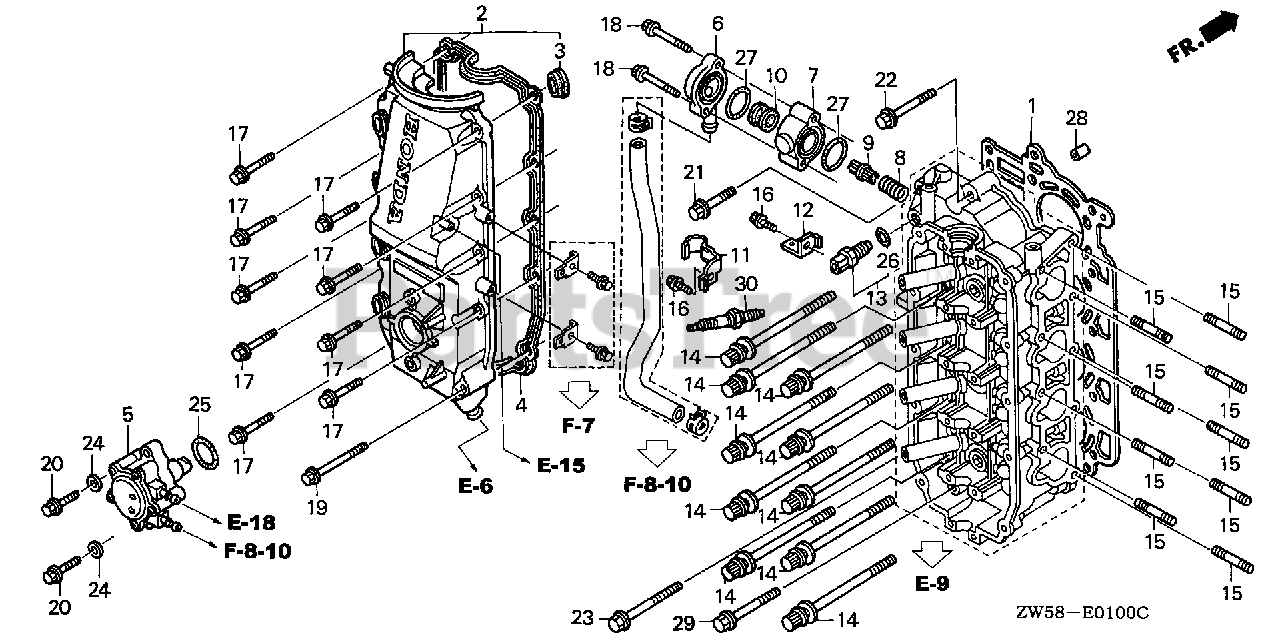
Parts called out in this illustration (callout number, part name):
1	GASKET, CYLINDER HEAD
2	COVER, HEAD *NH8* (DARK GRAY)
3	SEAL, SPARK PLUG TUBE (NOK)
4	GASKET, HEAD COVER
5	PUMP ASSY., FUEL (MSDS)
6	COVER, FLUSH VALVE
7	SPACER, FLUSH VALVE *NH8* (DARK GRAY)
8	SPRING, FLUSH VALVE
9	VALVE, RELIEF
10	GASKET, RELIEF VALVE
11	CLAMP, HOSE
12	STAY A, IGNITION WIRE CLAMP
13	SENSOR ASSY., WATER TEMPERATURE
14	BOLT-WASHER (12X163)
15	BOLT, STUD (10X32)
16	BOLT, FLANGE (6X12) (CT200)
17	BOLT, FLANGE (6X35)
18	BOLT, FLANGE (6X55)
19	BOLT, FLANGE (6X65)
20	BOLT, FLANGE (8X32)
21	BOLT, FLANGE (8X50)
22	BOLT, FLANGE (10X70)
23	BOLT, FLANGE (10X90)
24	WASHER, PLAIN (8MM)
25	O-RING (37X2.4) (ARAI)
26	O-RING (9.5X1.5) (HONDA KIKAKI)
27	O-RING (31.5X2.4) (ARAI)
28	PIN, DOWEL (14X20)
29	BOLT, FLANGE (8X80)
30	SPARK PLUG (KJ22CR-L8)
30	SPARK PLUG (ZFR7F)
